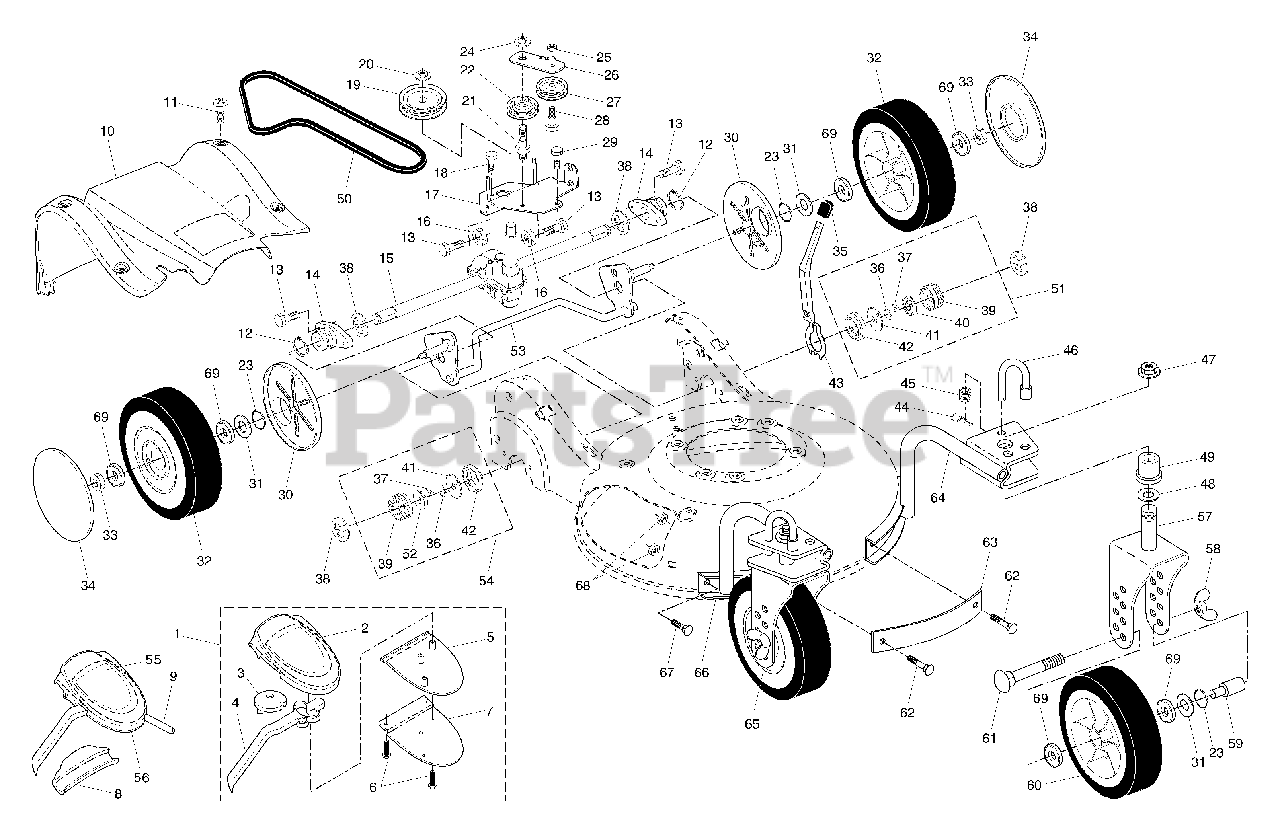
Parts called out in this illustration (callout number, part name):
1	Drive Control Assembly, Complete
2	Cover, Drive Control, Top
3	Pulley, Drive Control
4	Lever, Drive Control (blue)
5	Cover, Drive Control, Bottom
6	Screw, Torx Head #8-5/8
7	Bracket, Mounting, Drive Control
8	Cap, Drive Control, Bottom
9	Cable, Drive Control
10	Cover Assembly, Drive
11	Screw, Hex Washer Head 1/4-20 x 1/2
12	Ring, Retaining
13	Screw
14	Bearing / Axle Support
15	Gear Case Assembly (See Breakdown)
16	Nut, Hex
17	Bracket, Gear Case / Drive Pulley
19	Pulley, Drive
20	Nut, Hex, Flangelock
21	Bolt, Idler
22	Pulley Assembly, V-Groove
23	O-Ring
24	Nut, Hex, Flangelock
25	Nut, Hex, Lock
26	Idler Arm
27	Pulley, Idler
28	Bolt, Hex Head, Shoulder
29	Screw 1/4-20 x 1/16
30	Cover, Dust, Wheel
31	Washer, Flat 3/8
32	Wheel Assembly, Rear 9 x 2-1/4
33	Nut, Hex
34	Hubcap
36	Spring, Torsion
40	Retainer, Drive, LH
41	Disc, Drive
42	Seal, Friction
43	Lever, Selector, Wheel Height, Rear
47	Nut, Hex, Flangelock
48	Washer, Flat 1/2
49	Bushing
50	Belt, Drive
51	Pinion Assembly, LH
52	Retainer, Drive, RH
53	Rear Axle Assembly
54	Pinion Assembly, RH
55	Decal, Drive Control
56	Decal, Drive Control Adjustment (bottom)
57	Bracket, Caster Wheel, LH
58	Wing Nut 5/16-18
60	Wheel Assembly, Front 9 x 2
61	Bolt, Carriage 5/16-18 x 3-1/2
62	Bolt, Carriage 5/16-18 x 7/8
63	Strap, Front
64	Support Tube Assembly, LH
65	Bracket, Caster Wheel, RH
66	Support Tube Assembly, RH
67	Bolt, Carriage 5/16-18 x 5/8
68	Nut, Hex 5/16
69	Bearing, Ball (Wheel)
